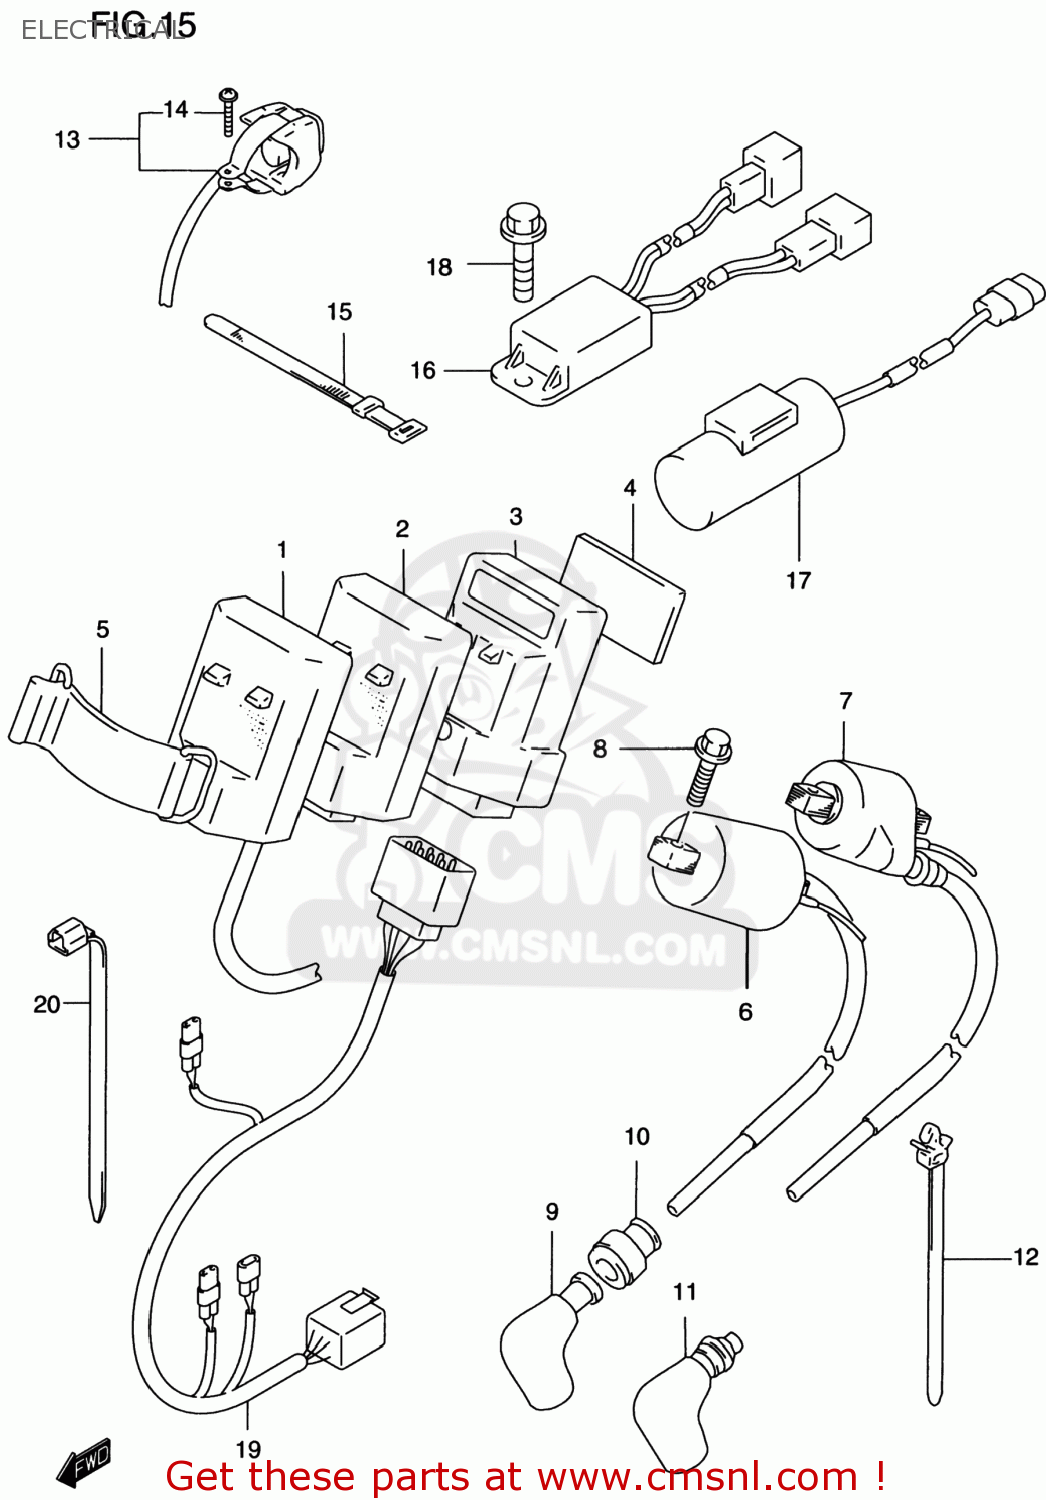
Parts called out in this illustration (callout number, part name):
1	CDI UNIT
2	CDI UNIT
3	CDI UNIT
4	PROTECTOR(170X95X3.0)
5	BAND,CDI UNIT(L:80)
6	COIL ASSY,IGNITION
7	COIL ASSEMBLY,IGNITION
8	BOLT
9	CAP,SPARK PLUG
10	SEAL,HIGH TENSION CORD
11	CAP,SPARK PLUG
12	CLAMP
13	SWITCH ASSY,ENGINE STOP
14	SCREW
15	CLAMP(L:120)
16	RECTIFIER ASSY
17	CONDENSER ASSY
18	BOLT
19	HARNESS,WIRING
20	CLAMP(L:235)
